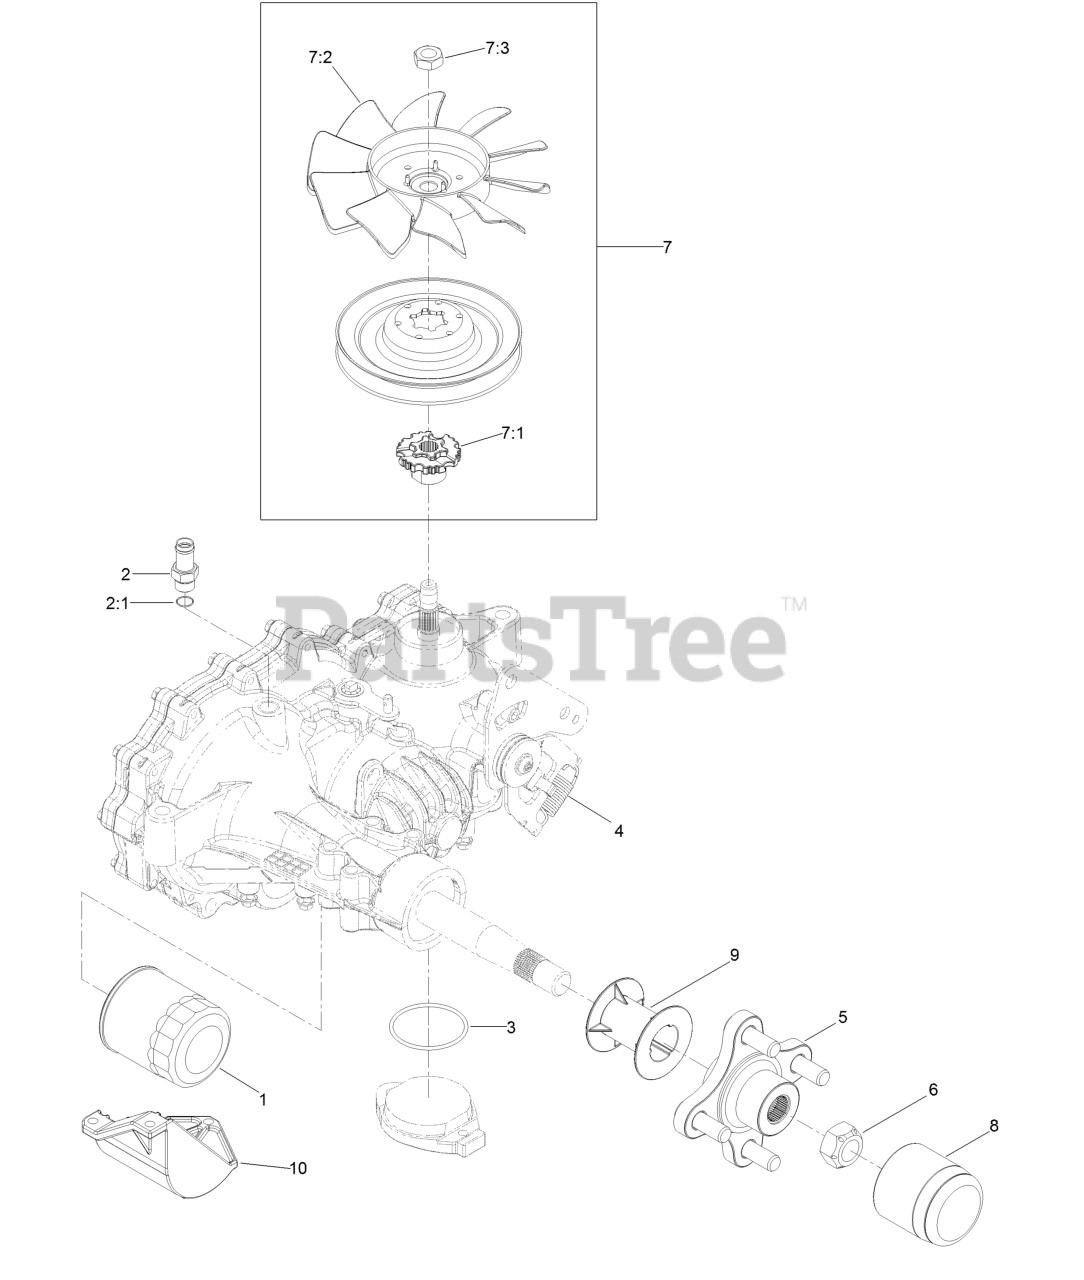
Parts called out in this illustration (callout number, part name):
1	Element-Oil Filter, HYD
2	Adapter-Straight
2:1	O-Ring
3	O Ring-Seal
4	Spring-Extension
5	Hub-Offset
6	Nut-Hub
7	Fan And Pulley Kit
7:1	Hub-Fan
8	Cap-Axle, Long
9	Tube-Axle
10	Guard-Filter, RH
11	Seal Kit
99	Brake Shaft Seal Kit
